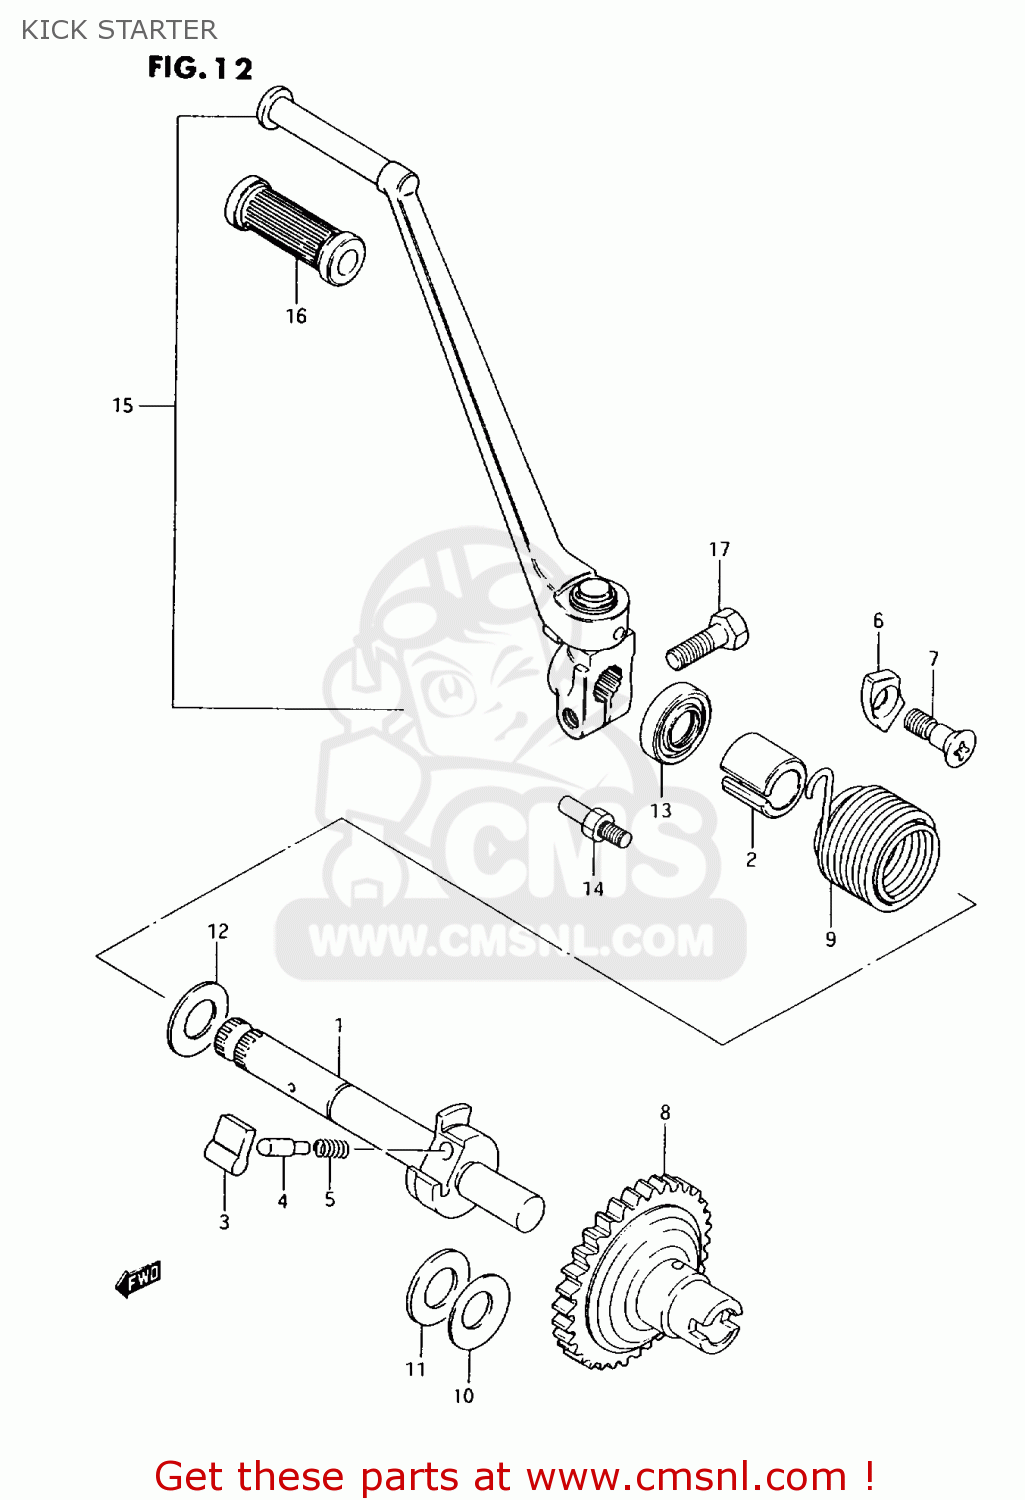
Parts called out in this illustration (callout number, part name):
1	SHAFT,KICK STARTER
2	GUIDE,KICK STARTER SFT SPRING
3	PAWL,KICK STARTER
4	PIN(5X15.5)
5	SPRING
6	LIFTER,KICK STARTER PAWL
7	SCREW ,6X16
8	GEAR,KICK STARTER DRIIVE
9	SPRING
10	WASHER
11	WASHER
12	WASHER(16X30X0.5)
13	SEAL,OIL(16X30X8)
14	BOLT,KICK START SHAFT SPR HOOK
15	LEVER ASSY, KICK STARTER
16	RUBBER,KICK STARTER PEDAL
17	BOLT
